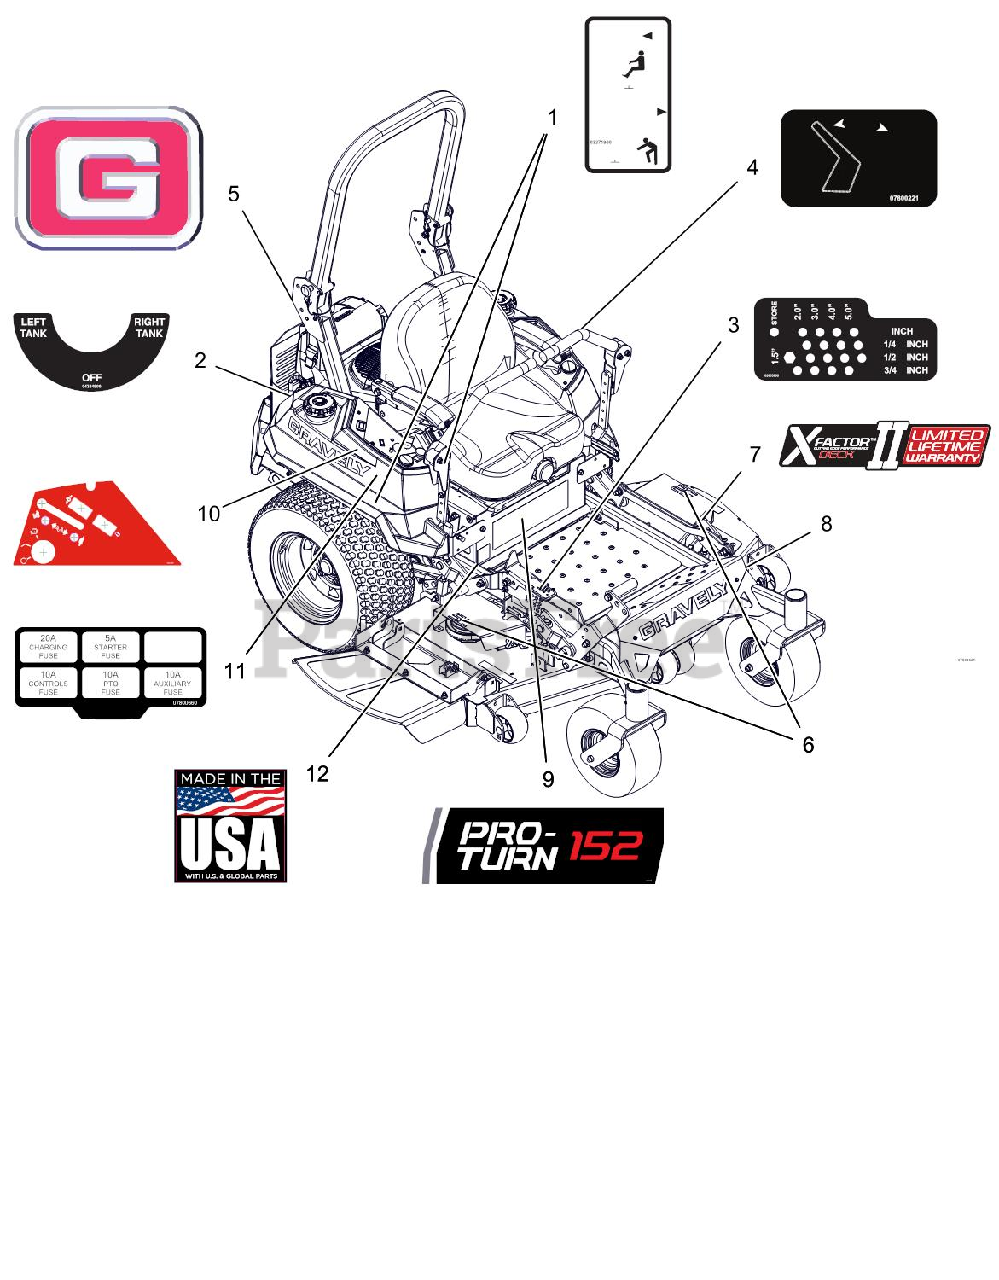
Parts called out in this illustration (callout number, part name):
1	DECAL, TRANSMISSION DISCONNECT
2	DECAL, FUEL VALVE
3	DECAL, HEIGHT OF CUT
4	DECAL - SEAT RELEASE
5	DECAL, GRAVELY BRAND
6	DECAL, 52"
7	DECAL, X-FACTOR DECK
8	DCL,BELT ROUTE-RH V-SIDE IDLER
9	DECAL, PRO-TURN 152
10	DECAL, EFI CONTROL PANEL
11	DECAL, FUSE BLOCK
12	DECAL, MADE IN USA
